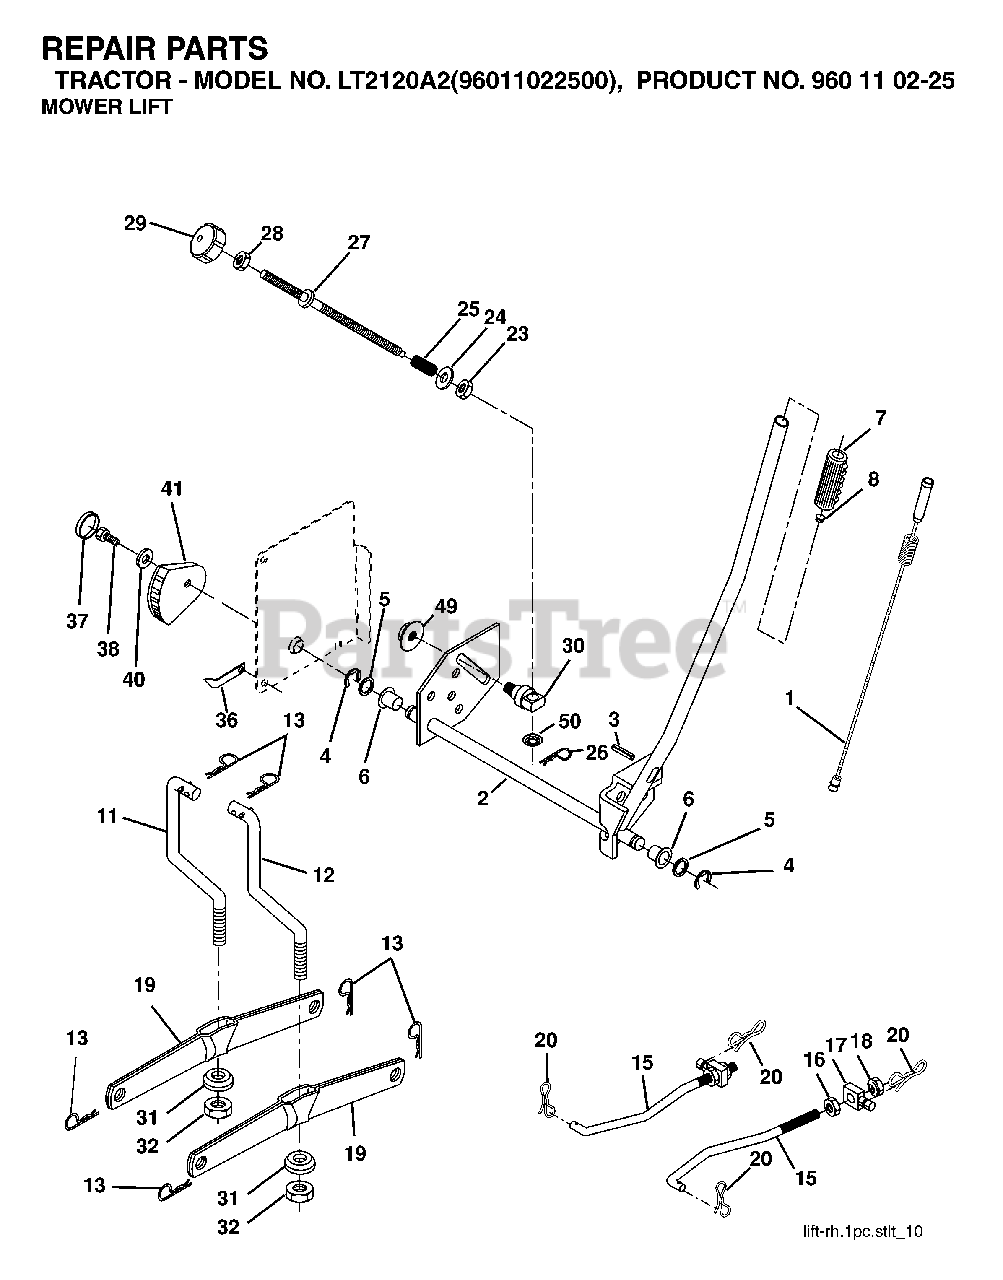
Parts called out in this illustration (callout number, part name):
4	RETAINING RING LT
6	BEARING.NYLON
7	GRIP HANDLE
11	LINK LIFT LH
12	LINK LIFT RH
13	RETAINER-SPRNG RB
15	LINK.SUSPENSION.FRONT
16	NUT
18	NUT
19	ARM.REAR.SUSPENSION
20	PIN.COTTER.7/16.BOW TI
26	RETAINER CLIP
28	NUT
29	KNOB INF 3/8-16
31	BEARING.PIVOT.LIFT
32	NUT CROWNLOCK 3/8-24
36	POINTER, HEIGHT INDICATOR
37	PLUG,HOLE
38	SCREW 5/16-18X1
41	IND. HEIGHT STLT
49	NUT
50	NUT PUSH M
